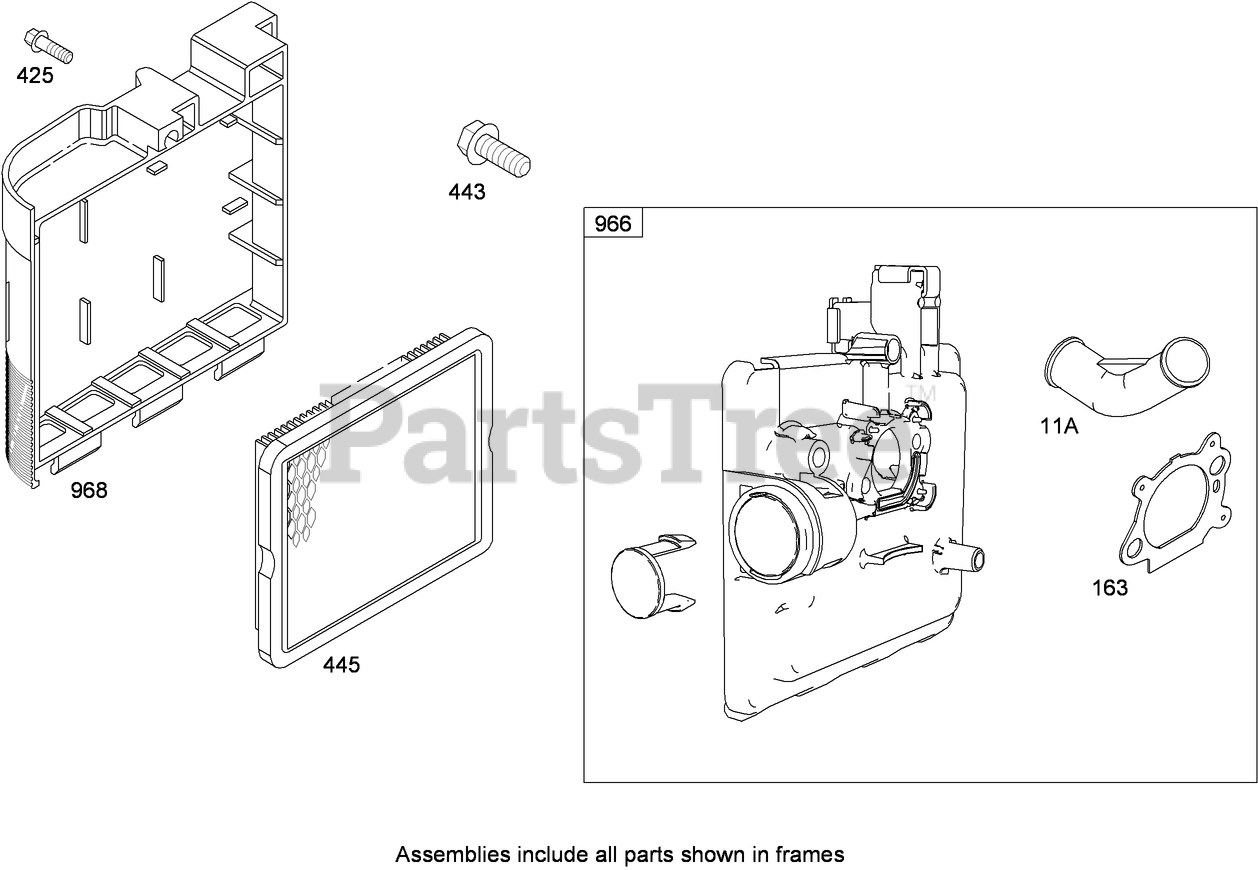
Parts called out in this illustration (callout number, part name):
11A	Grommet
163	Gasket-Cleaner, Air
425	Screw
443	Screw
445	Filter-Cartridge, Air Cleaner
966	Base-Primer, Air Cleaner
968	Cover-Cleaner, Air
